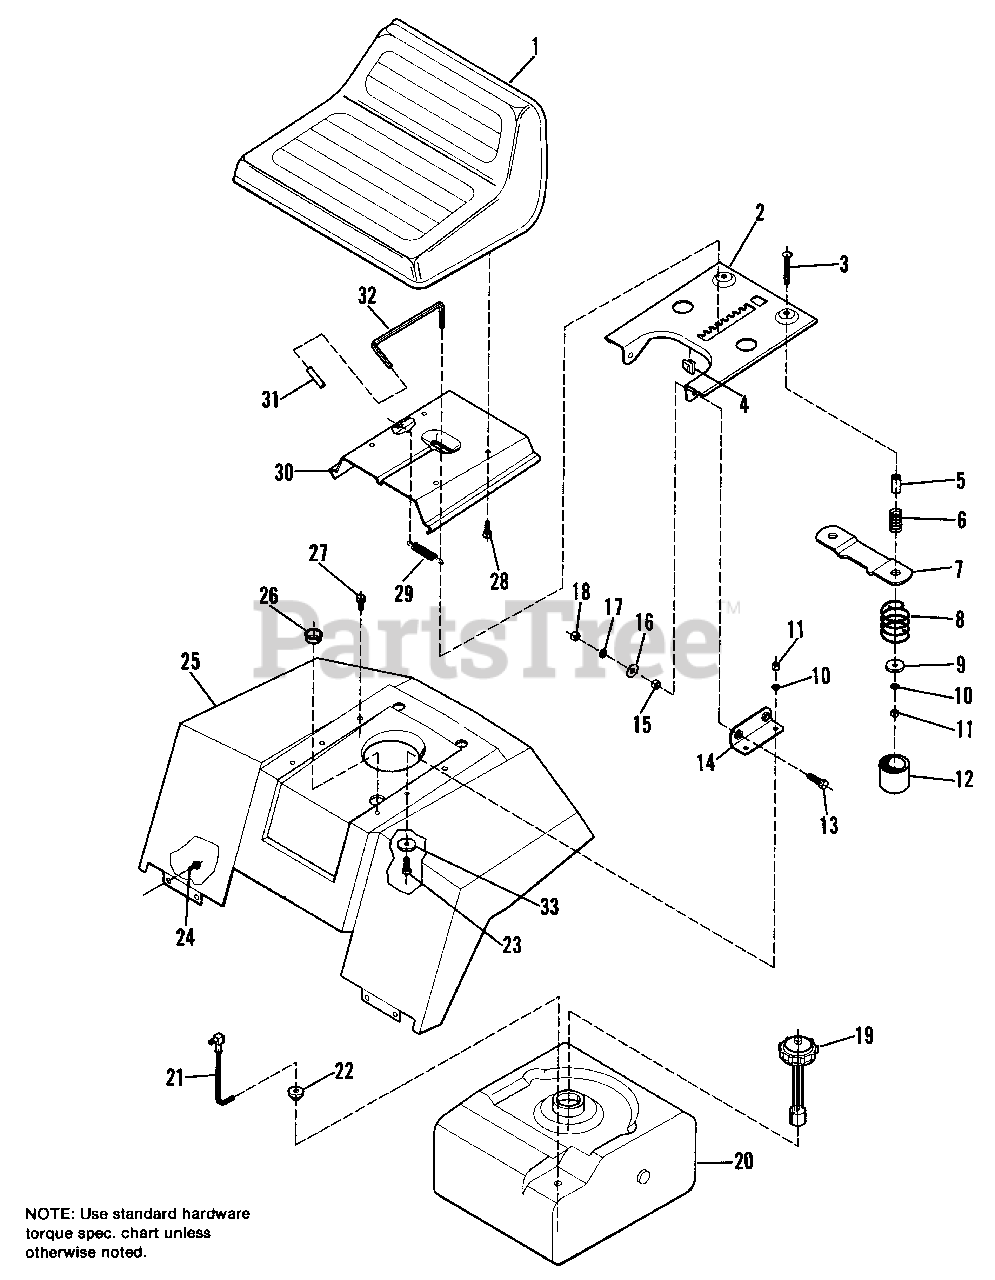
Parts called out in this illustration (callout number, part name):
2	PLATE, Seat
3	CARRIAGE BOLT, 5/16-18 x 2
4	CLIP, Speed
6	SPRING, Compression
7	PLATE, Switch
8	SPRING, Compression
9	WASHER, Plain
10	LOCKWASHER, 5/16
11	NUT, Hex, Full, 5/16-18
12	COVER, Spring
13	CAPSCREW, Hex Hd., 3/8-16 x 1
14	BRACKET, Seat Suspension
16	WASHER, Plain, 13/32
17	LOCKWASHER, 3/8
18	NUT, Hex Hd., 3/8
19	CAP, Fuel Gauge
20	TANK, Fuel
21	ELBOW & TUBE ASSY.
23	CAPSCREW, Hex Hd., 5/16-18 x 3/4
24	SCREW, Taptite, 1/4-20 x 1/2
26	BUSHING, Snap
27	SCREW, Taptite, 5/16-18 x 5/8
28	BOLT, Hex, Whizlock, 5/16-18 x 3/4
30	BRACKET, Seat Slide
31	HANDLE, Grip
32	LEVER, Seat Release
33	WASHER, Plain
